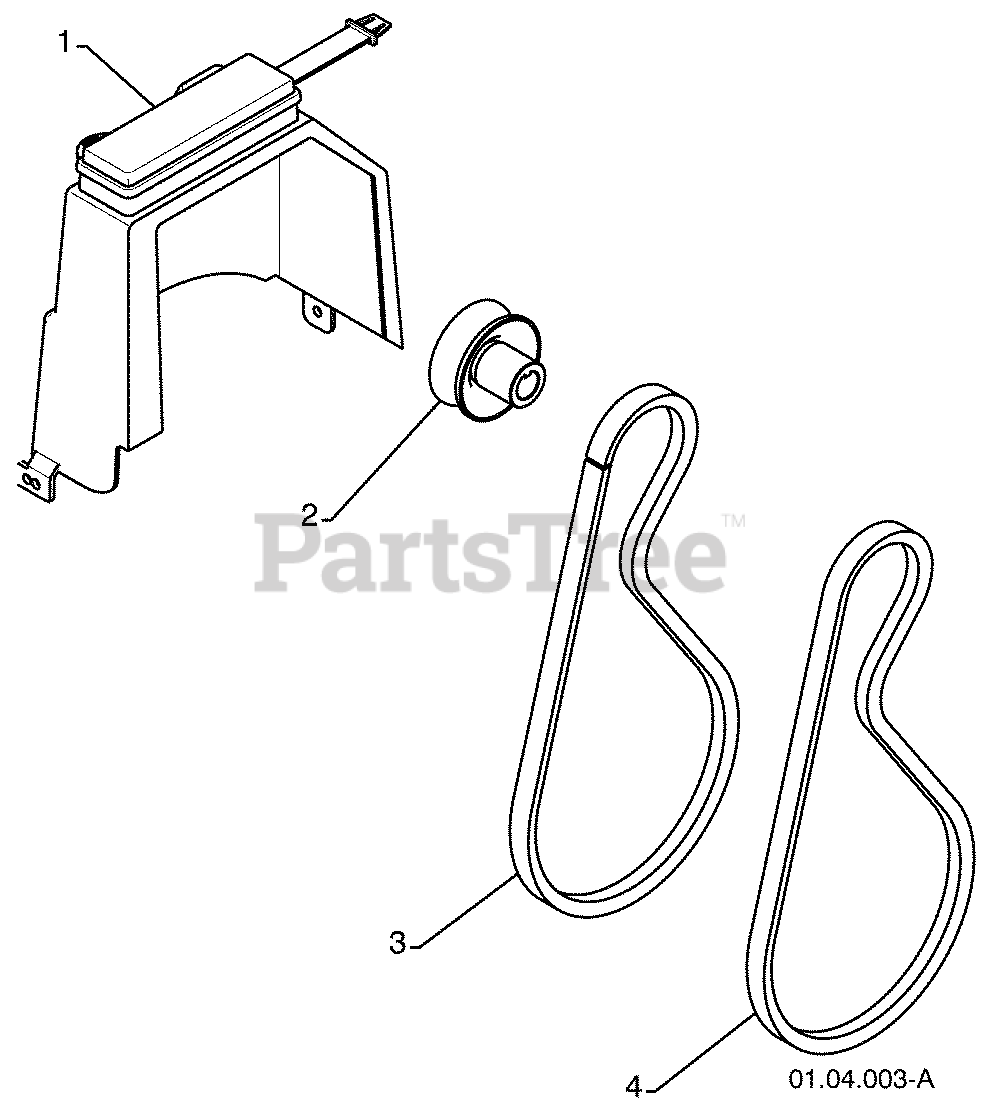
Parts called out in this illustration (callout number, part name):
1	COVER ASSEMBLY
2	PULLEY
3	TRACTION BELT
4	IMPELLER BELT
